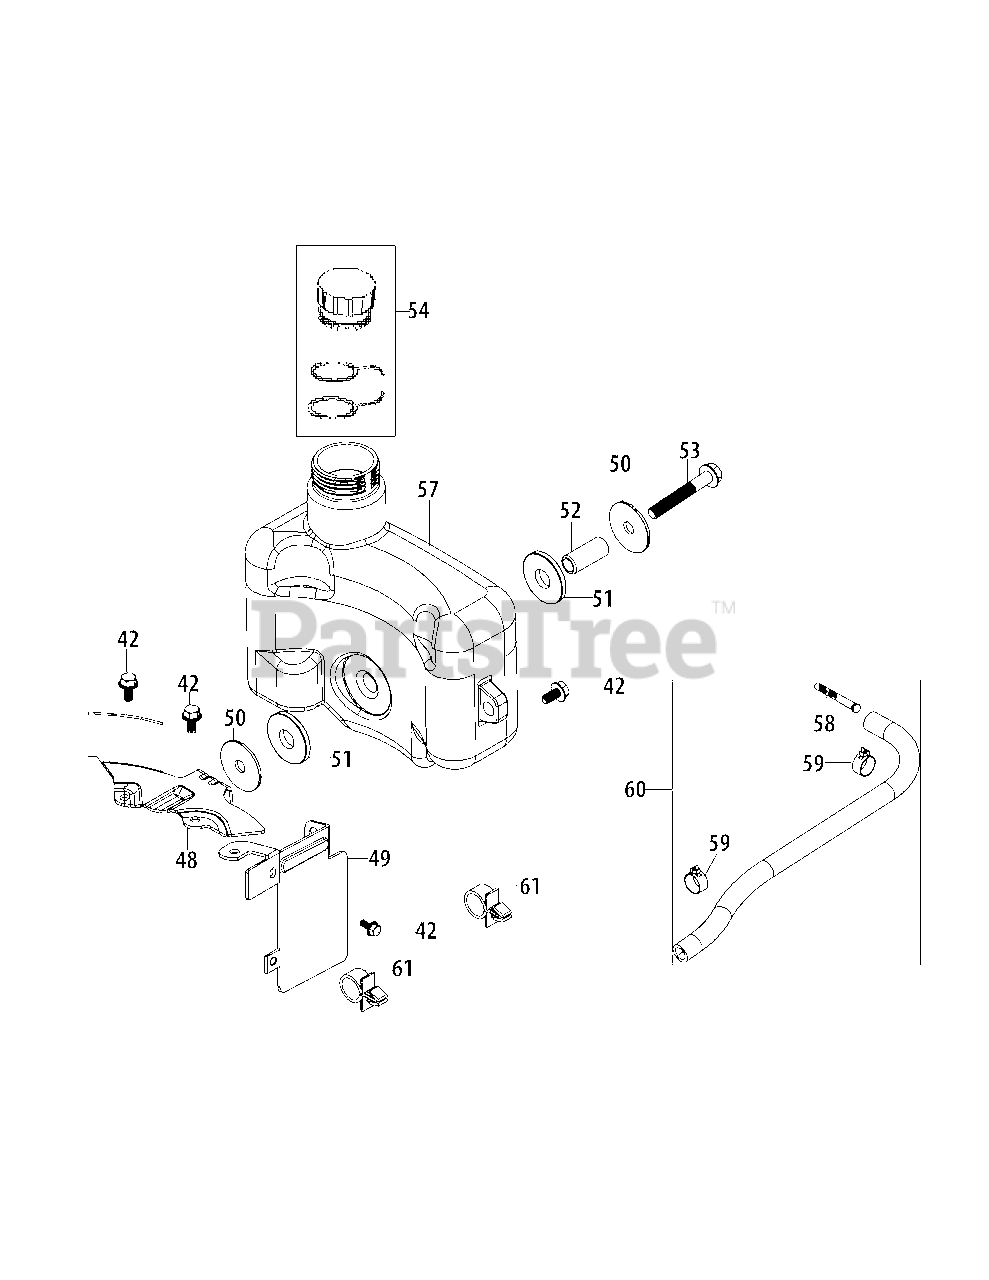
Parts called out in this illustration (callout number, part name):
48	Fuel Tank Bottom Bracket
49	Fuel Tank / Label Bracket
50	Fuel Tank Washer
51	Rubber Bushing
52	Fuel Tank Bushing
53	Bolt M8X50
54	Fuel Cap Assembly
57	Fuel Tank Assembly
58	Fuel Filter
59	Fuel Hose Clamp
60	Fuel Line Kit
61	Plastic Support Clamp
